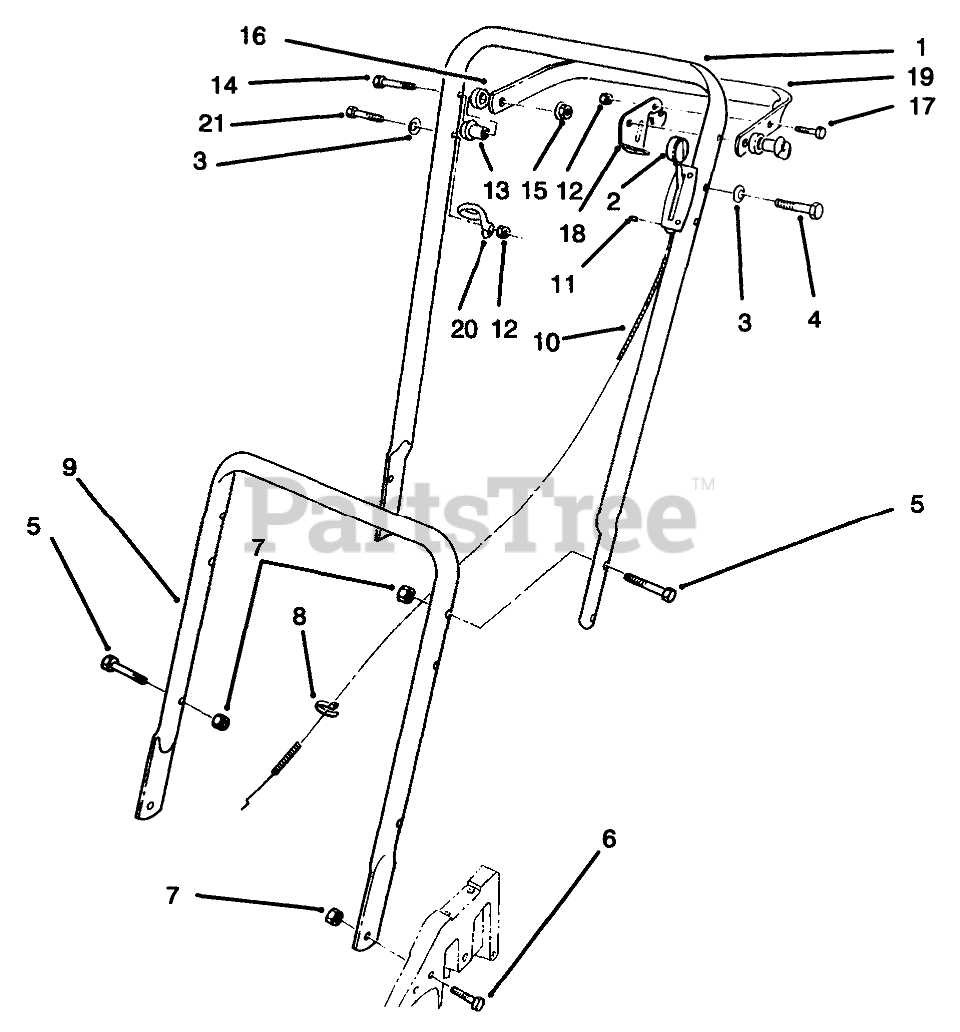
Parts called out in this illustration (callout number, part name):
1	Handle-Upper
2	CONTROL-THROTTLE
3	WASHER
4	SCREW-HH
5	SCREW-HH
6	SCREW-HH
7	NUT-LOCK, NI
8	TIE-CABLE
9	Handle-Lower
10	CABLE-THROTTLE
11	E-RING
12	NUT-LOCK, NI
13	SPACER-SUPPORT
14	SCREW-HH
15	NUT-LOCK, NI
16	SPACER-NYLON
17	SCREW-HH
18	LEVER-CONTROL
19	Bar-Control
20	GUIDE-ROPE
22	SCREW-HH
